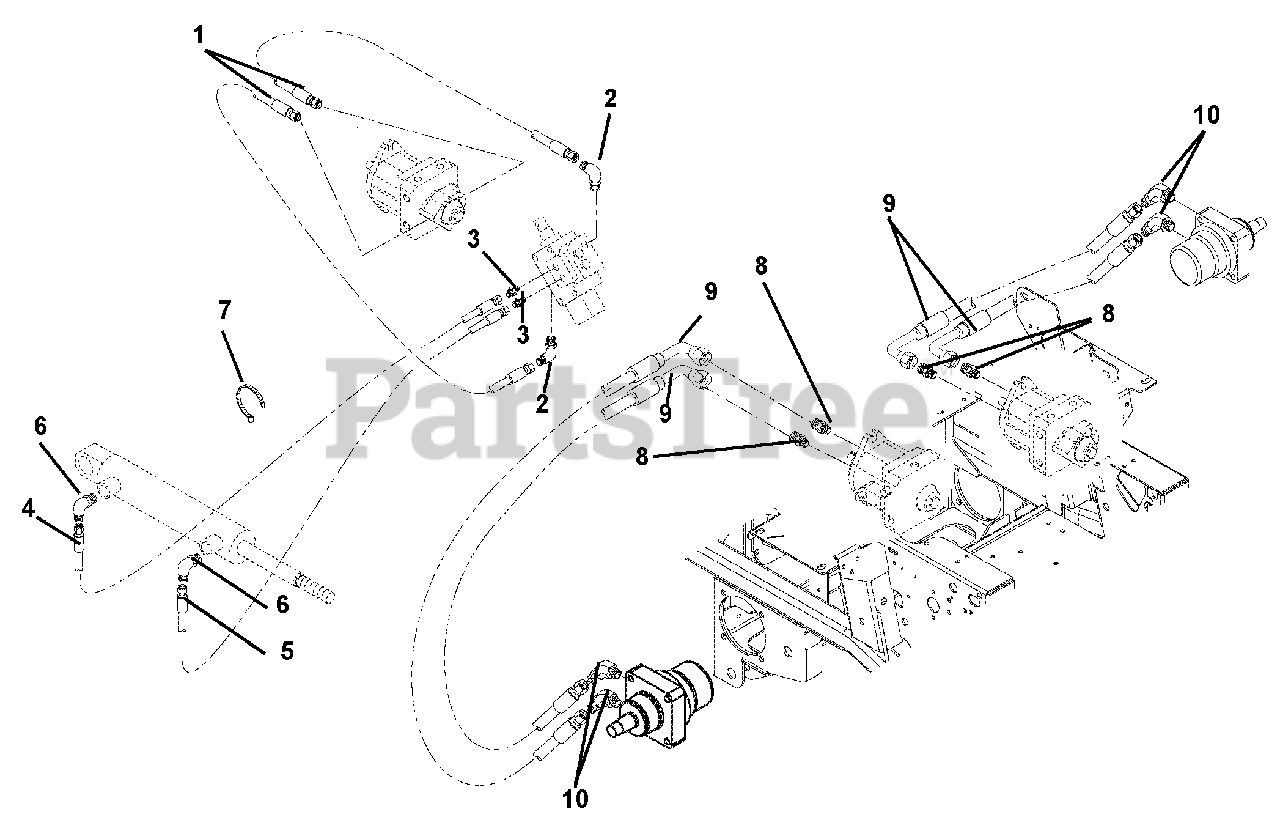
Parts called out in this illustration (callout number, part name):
1	HOSE,HYD.25-22-2K F04F9-F06FO
2	FTG, HYD ELBOW M6F-M8O
3	FITTING, HYD (4-6 F5OLO)
4	HOSE,HYD.25-42-2K F04F0-F04F4
5	HOSE,HYD .25-47-2K F04F0-F04F4
6	FITTING, HYD (4 C5OLO)
7	CABLE TIE LG 5-1/2
8	ADPTR,FACE SEAL 8X8 1/2 O-RING
9	HOSE,HYD .50-17-2K F08F0-F08F9
10	FITTING, HYD (8-10 V5OLO)
